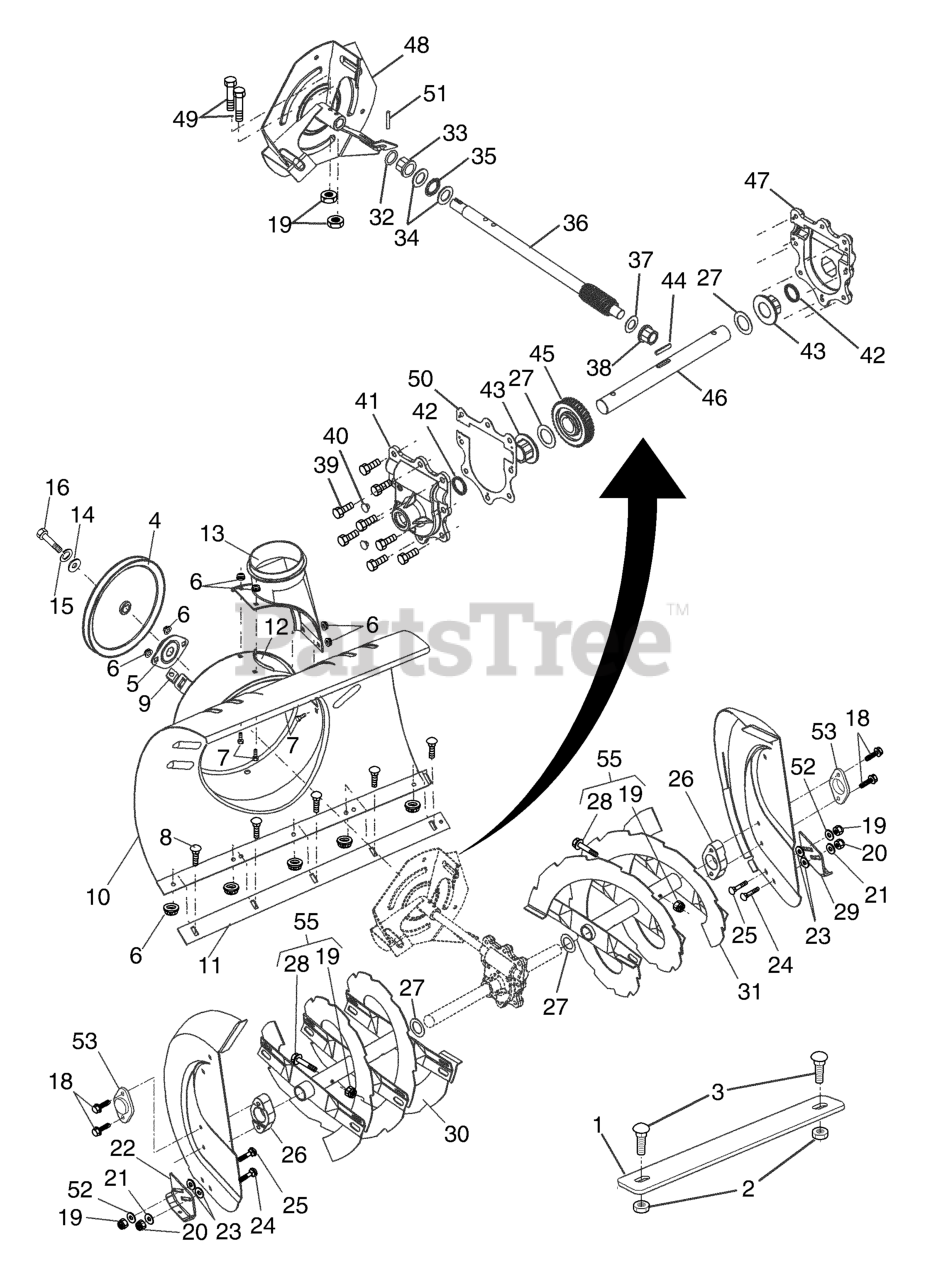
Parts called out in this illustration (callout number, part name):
1	WEIGHT, AUGER HOUSING 27
2	LOCKNUT 5/16-18
3	BOLT.CARRIAGE.5/16-18
4	PULLEY, IMPELLER
5	BEARING FLANGE
6	NUT.FLANGE.5/16
7	BOLT.CARRIAGE.5/16-18X
8	BOLT
9	NUT, CAGE 3/8-16
10	HOUSING, AUGER 27"
11	BAR, SCRAPER 27"
12	BRACKET, CORNER DISCHARGE
13	BASE DISCHARGE CHUTE
14	WASHER, FLAT
15	WASHER.LOCK.HVY.HLCL.SPR.5/16
16	Screw, Hex Head 5/16-18 x 3/4
18	SCREW, HEX HD 5/16X1
19	LOCKNUT.NYLOC.1/4-20
20	NUT.71038.31-18.HEX.NYLOCK
21	WASHER.20X8.5
22	SKID PLATE RH
23	WASHER, NYLON FRICTION
24	BOLT
25	SHOULDER BOLT
26	BEARING RETAINER, PLASTIC
27	WASHER TRUST 1"
28	KIT, SHEAR BOLT
29	SKID PLATE LH
30	AUGER ASSY RH
31	AUGER ASSY LH
33	BUSHING FLANGE 3/4
34	WASHER, THRUST 3/4
35	BEARING TRUST 3/4 NTA-1220
36	SHAFT, IMPELLER
37	WASHER, THRUST 5/8
38	BUSHING.FLANGE.(.625X.75)
39	SELF-TAPPING SCREW 5/16-18X3/4
40	PLUG.AUGER.GEAR.BOX.SNOW
41	HOUSING.GEARBOX.RH.SNOW
43	BUSHING FLANGE 1"
44	KEY
45	WORM GEAR
46	SHAFT, AUGER
47	LH GEARBOX HOUSING
48	IMPELLER ASSY
49	SCREW.HEX.HD1/4-20X
50	GASKET.AUGER.GEARBOX
51	PIN, ROLL 3/16 X 1-1/8
52	WASHER
53	BEARING.BALL.AUGER.SHAFT
55	KIT, BOLT, SHEAR
